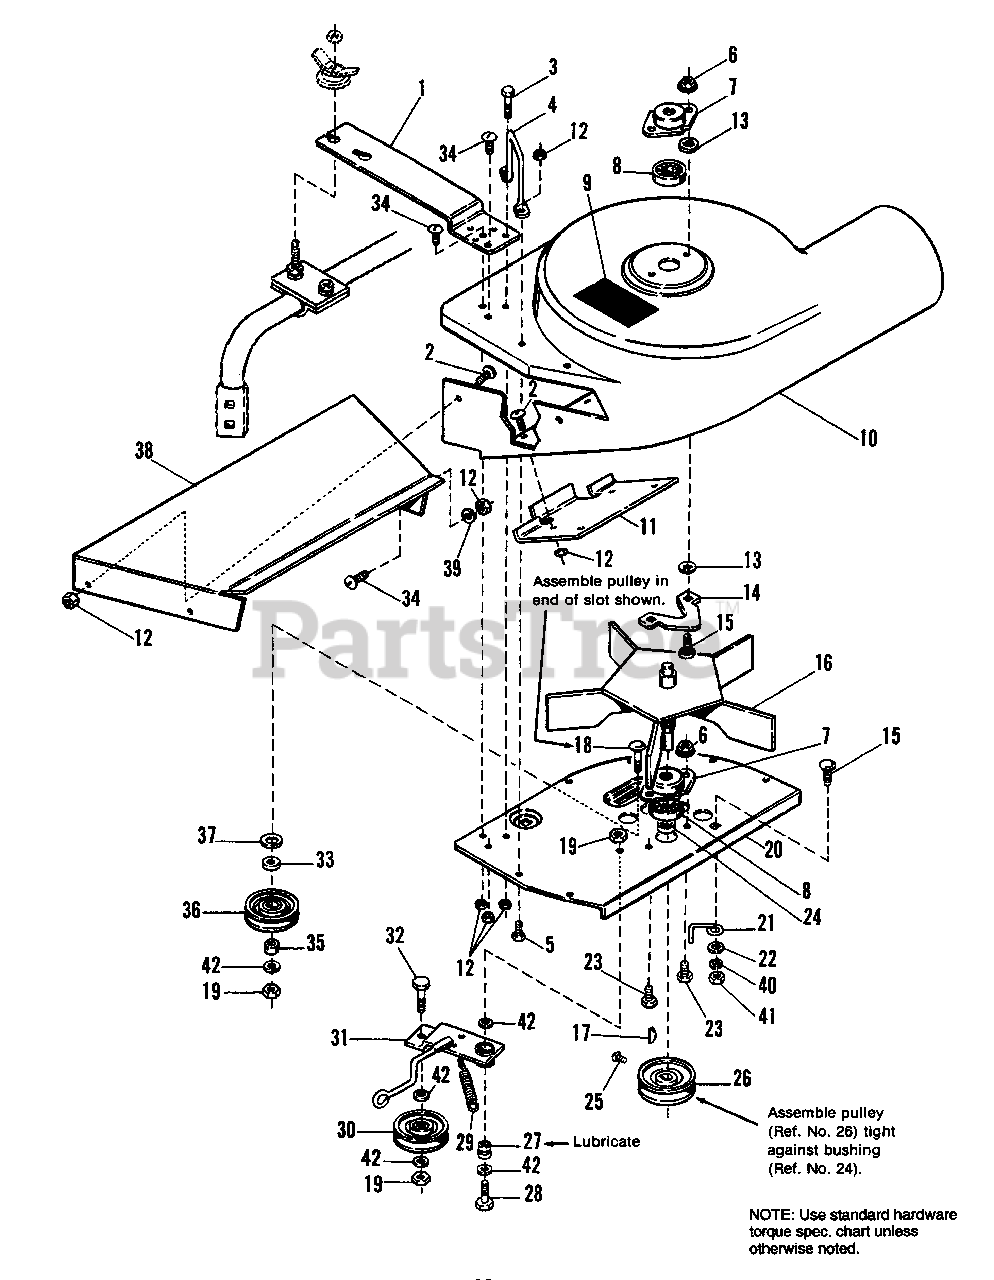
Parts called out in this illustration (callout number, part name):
1	MOUNTING PLATE, 60"
2	CAPSCREW, Hex Hd., 1/4-20 x 5/8
3	CAPSCREW, Hex, 1/4-20 x 2-1/4
4	STOP, Deflector
5	CAPSCREW, Hex, 1/4-20 x 7/8
6	NUT, Flange Lock, 5/16-18
7	BEARING, Retainer
9	DECAL, Warning
10	TURBO HOUSING
11	HOOK, Stoneguard
12	NUT, Hex Lock Nylon, 1/4-20
13	PUSHNUT, 5/16 Stud
14	PLATE, Range
15	CARRIAGE BOLT, 5/16-18 x 3/4
16	FAN ASSY. (5 Blade)
17	KEY, Woodruff
18	CARRIAGE BOLT, 3/8-16 x 1-1/4
19	NUT, Hex Jam Lock, 3/8-16
20	PLATE, Shroud
22	WASHER, Plain, 11/32
23	CAPSCREW, Hex, Thin Hd., 5/16-18 x 3/4
25	SET SCREW, Socket Hd., 5/16-18 x 3/8
26	PULLEY, Driven
27	SPACER
28	CAPSCREW, Hex, 3/8-16 x 1-1/2
29	SPRING, Tension
30	PULLEY, Idler
31	IDLER ARM ASSY.
32	CAPSCREW. 3/8-16 x 1
33	WASHER, Special
34	SCREW, Truss Hd, 1/4-20 x 3/4
36	PULLEY, idler
37	WASHER, Plain, 1/2
39	WASHER, Plain, 9/32
40	WASHER, Spring
41	NUT, Hex, 5/16
42	WASHER, 13/32
